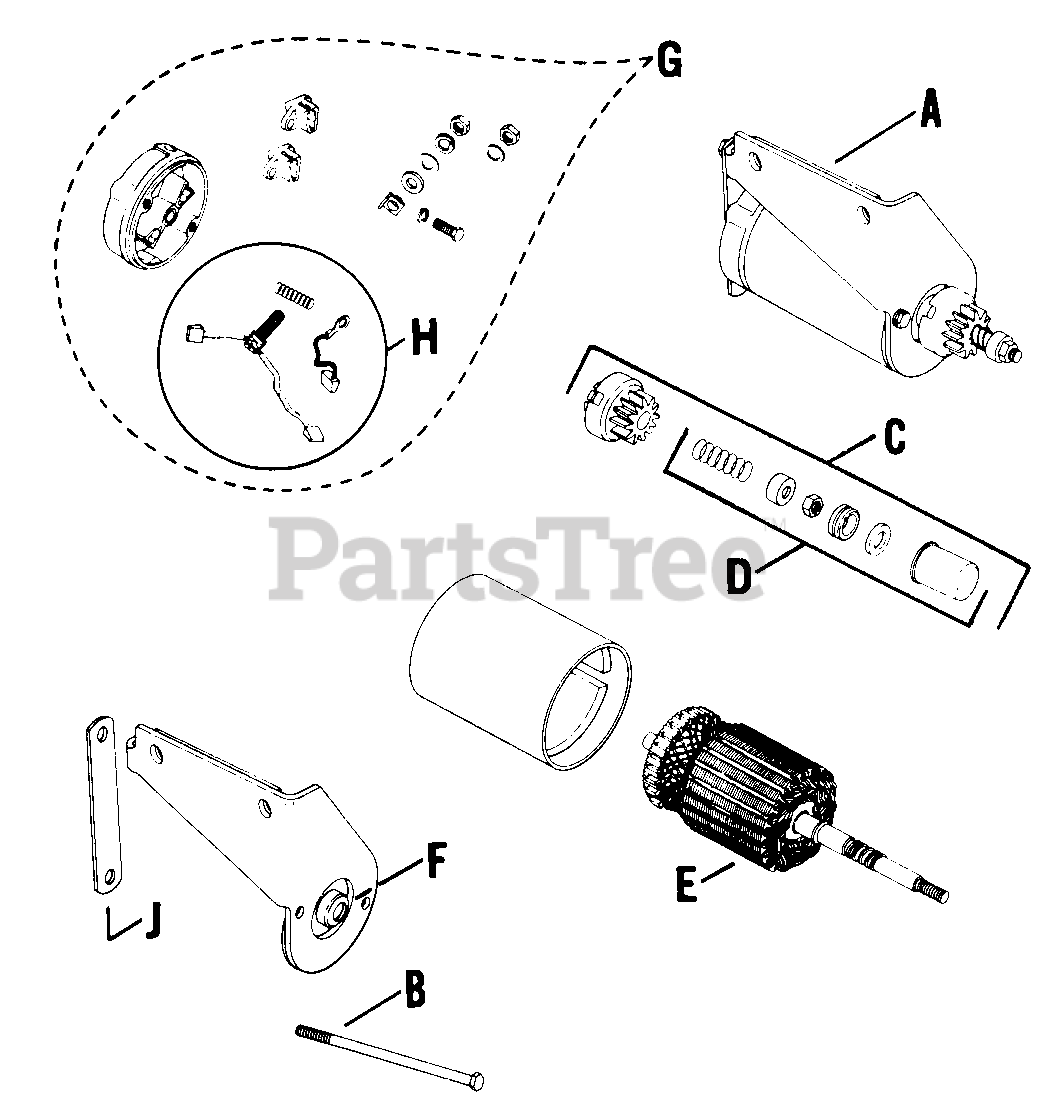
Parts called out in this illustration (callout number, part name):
A	STARTER - USE 41 098 01
A	STARTER - USE 41 098 03
B	BOLT - USE 237758
C	KIT - USE 41 755 15
F	BEARING - DISCONTINUED
G	CAP - DISCONTINUED
